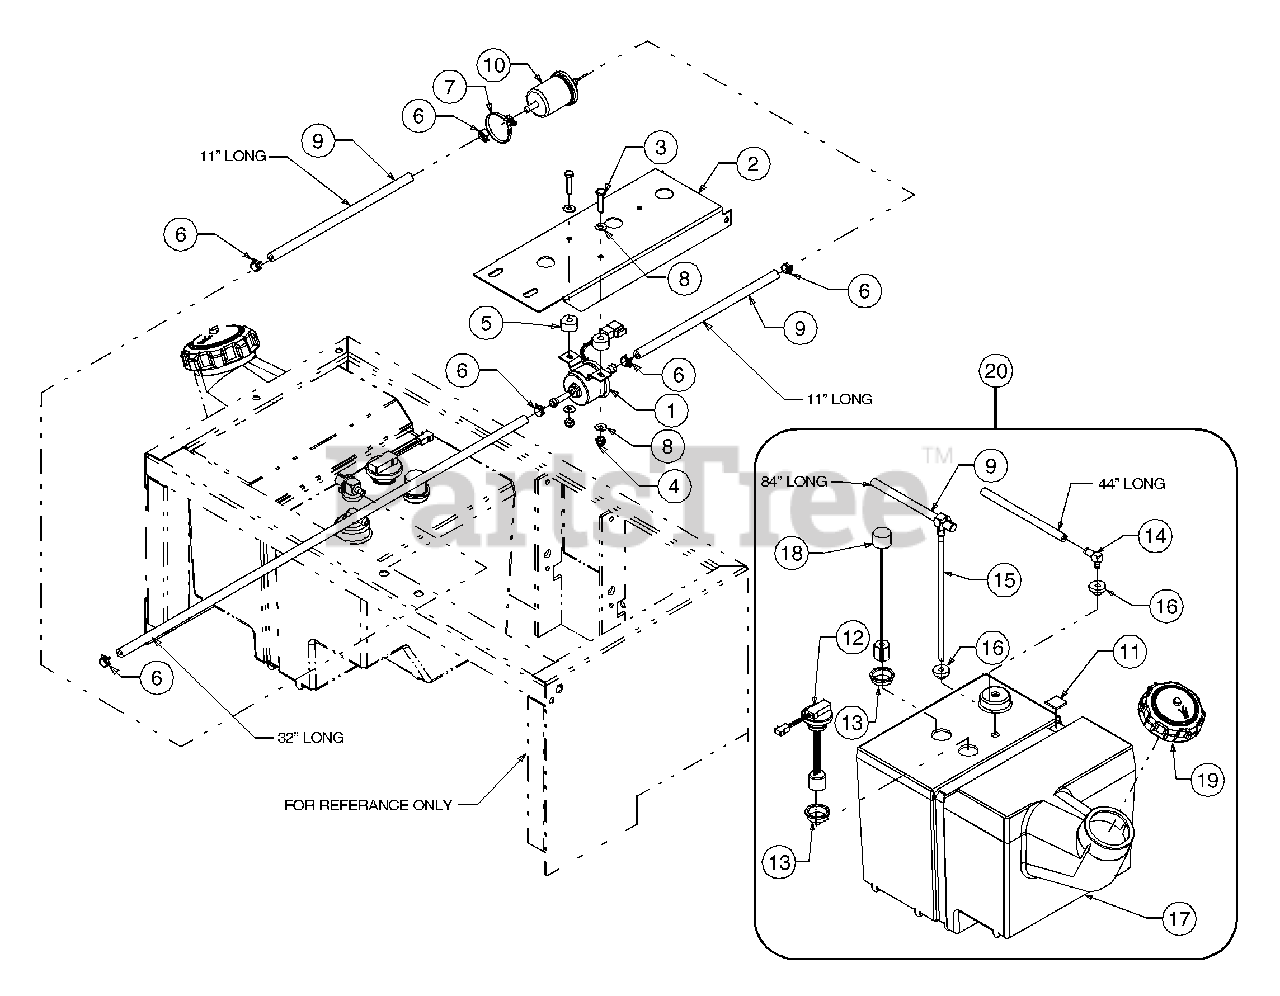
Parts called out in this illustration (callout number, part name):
1	Pump Assembly, Fuel
4	Nut, Nylon Hex Lock, 1/4-20, Gr8
5	Bushing, .96 OD x .50
6	Clamp, Hose
7	Cable Tie, 19 x 8.39
8	Washer, Flat, .271 x .630 x .065
9	Hose, Fuel Line
12	Switch, Fuel Level Gauge
13	Grommet, 1.58 OD x 1.21 ID x .5
14	Fitting, Elbow, .190 ID
15	Valve, Fuel Tank
16	Grommet, 1.06 OD x .362
17	Tank, Fuel
18	Gauge, Fuel Tank
19	Cap, Fuel, 3.5
20	Tank Assembly, Fuel
